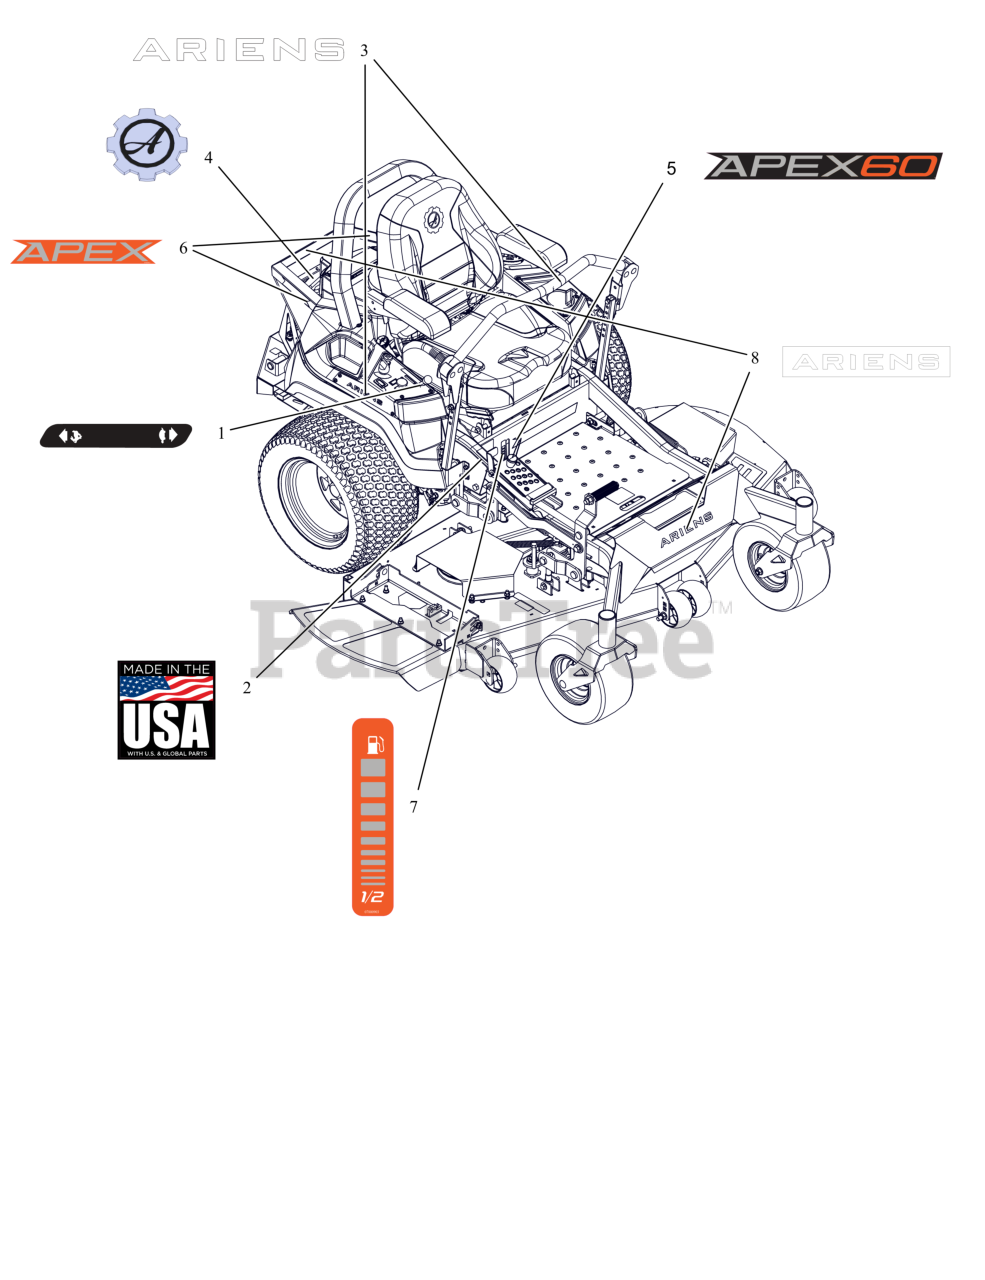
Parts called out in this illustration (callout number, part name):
1	DECAL, DASH DECAL
2	DECAL, MADE IN USA
3	DECAL, ARIENS (6.50")
4	DECAL, ARIENS-GEAR BADGE -THK
5	DECAL, 60" APEX KICKPLATE
6	DECAL, APEX FENDER
7	DECAL, ARIENS FUEL LEVEL
8	DECAL - ARIENS 9.625"
